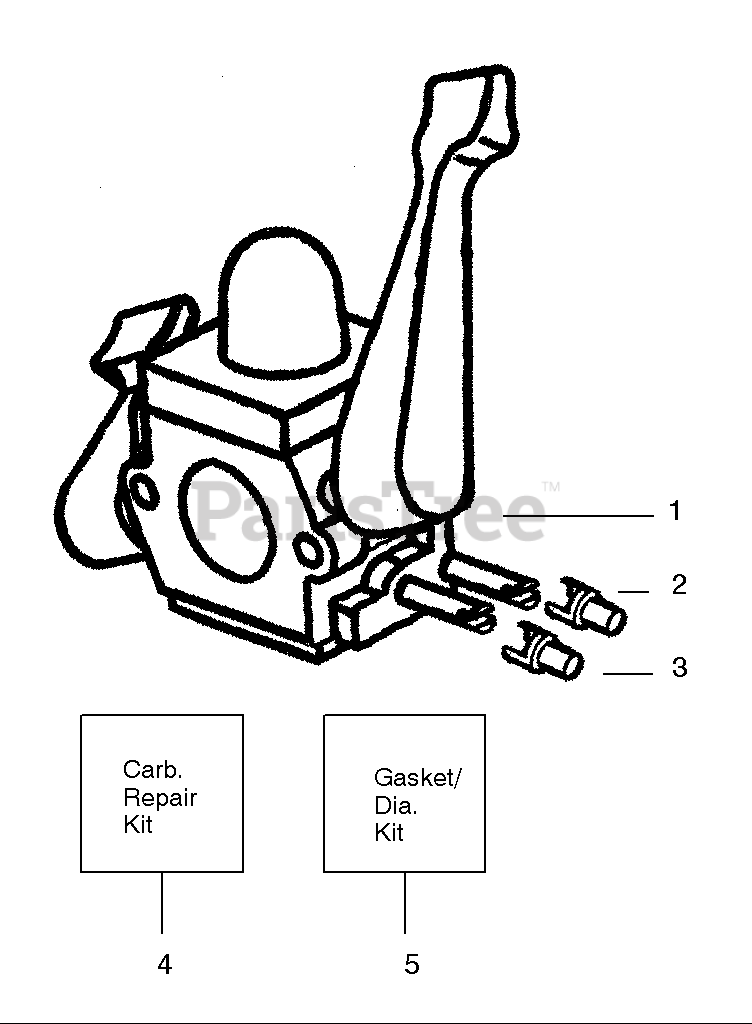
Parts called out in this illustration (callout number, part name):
1	Assy-Carb. Zama (C1Q-W11)
2	Cap-Limiter (high) brown
3	Cap-Limiter (low) tan
4	Kit-Carb. Repair
5	Kit-Dia. (GND-34)
